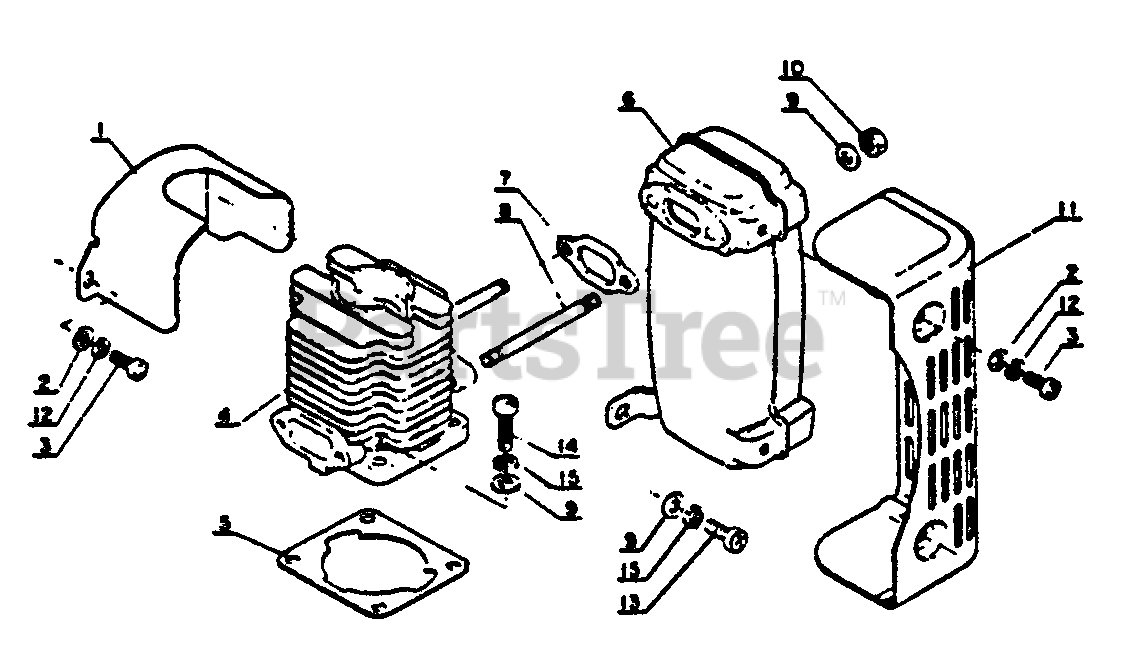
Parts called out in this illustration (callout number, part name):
1	SHIELD, CYLINDER
2	WASHER - 4
3	SCREW - 4X10
4	CYLINDER
5	GASKET, CYLINDER
6	MUFFLER
7	GASKET, EXHAUST
8	STUD
9	WASHER - 5
10	LOCKNUT - 5
11	COVER, MUFFLER
12	LOCKWASHER - 4
13	SCREW - 5X10
14	SCREW - 5X18
15	LOCKWASHER - 5
